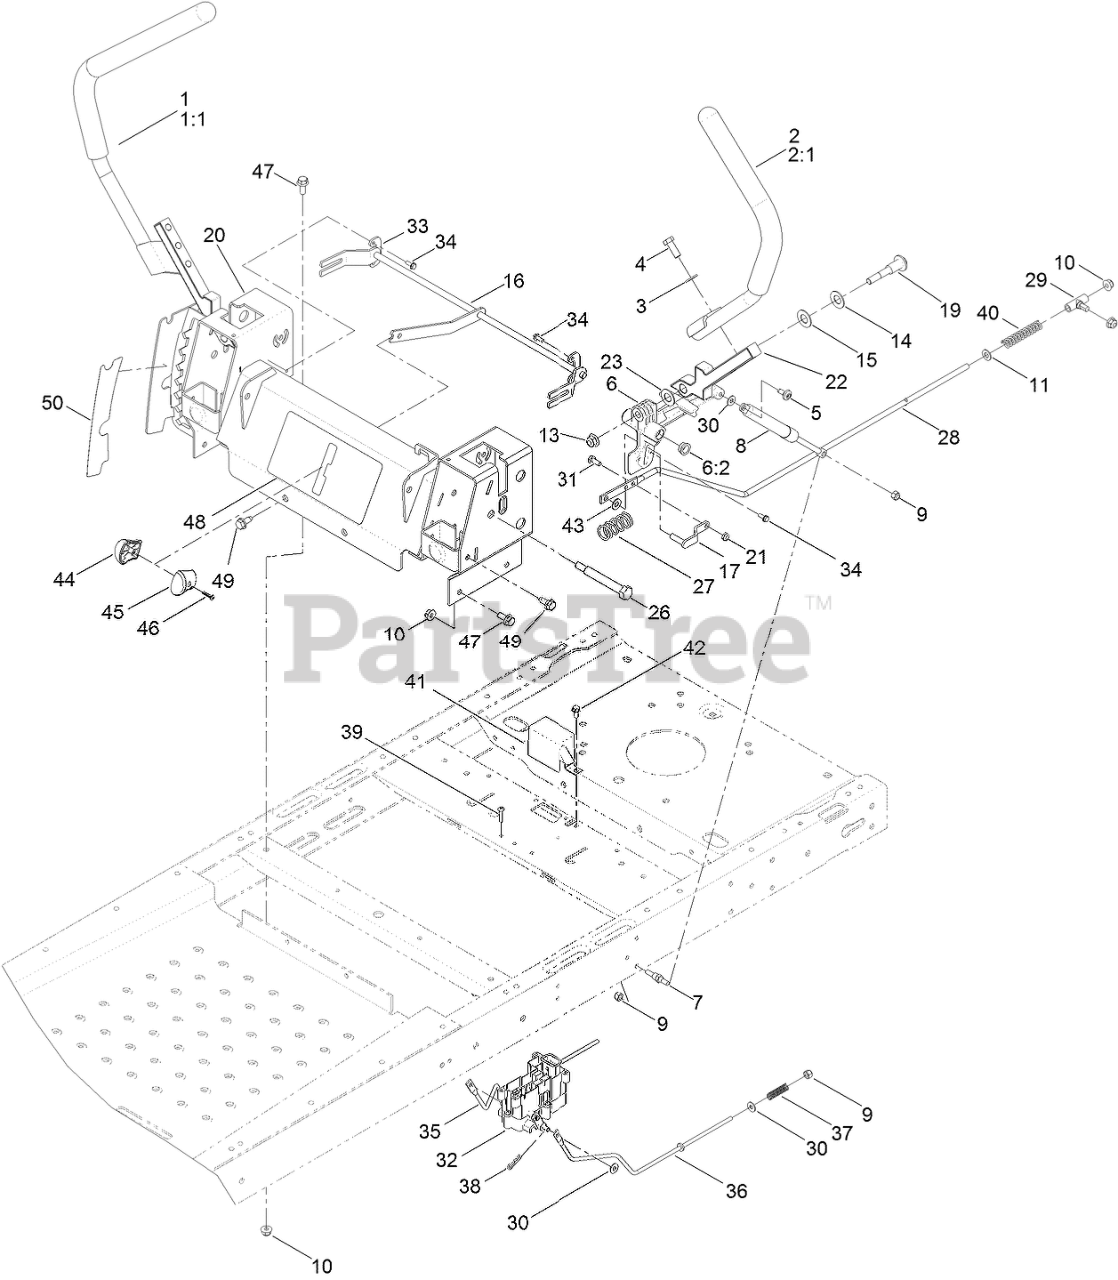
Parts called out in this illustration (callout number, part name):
1	HANDLE-CONTROL, RH
2	HANDLE-CONTROL, LH
3	WASHER-FLAT
4	SCREW-HH
5	SCREW-SHOULDER
6	ACTUATOR ARM ASM
6:2	BUSHING-FLANGE
7	STUD-DAMPER
8	Damper-Control, Motion
9	NUT-LOCK, NI
10	NUT-HF, NI
11	WASHER-PLAIN
13	NUT-HF, NI
14	WASHER-BELLEVILLE
15	WASHER
16	CONTROL-SPEED
17	PIN-ROD, HYDRO
19	BOLT-PIVOT
20	CONTROL BOX ASM
21	NUT-LOCK, NI
22	LEVER-CONTROL
23	WASHER-NYLON
26	BOLT-PIVOT
27	SPRING-RETURN
28	ROD-HYDRO
29	MOUNT-ROD, HYDRO
30	WASHER
31	SCREW-HH
32	BRAKE CONTROL MODULE ASM
33	RETAINER
34	SCREW-TAPTITE
35	ROD-BRAKE, RH
36	ROD-BRAKE, LH
37	SPRING-COMPRESSION
38	PIN-COTTER
39	SCREW-PPH
40	SPRING-RETURN, NEUTRAL
41	COVER-BRAKE
42	SCREW-HWH
43	SPACER-NYLON
44	KNOB-RH
45	KNOB-LH
46	SCREW-PPH
47	SCREW-HHF
48	DECAL-SPEED CONTROL
49	SCREW-HWHTF
50	DECAL-HOC, CE
